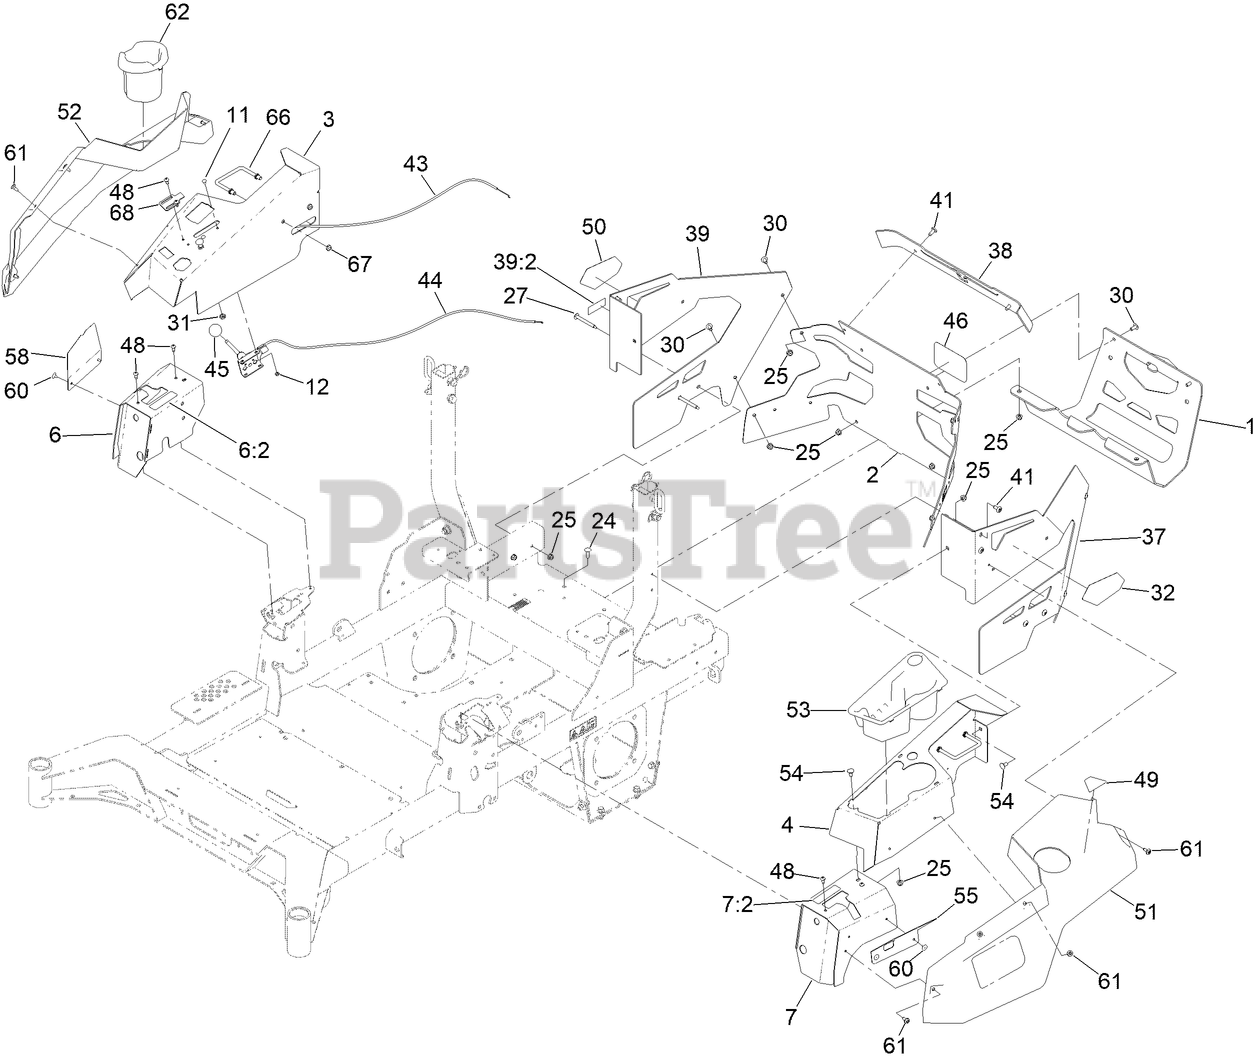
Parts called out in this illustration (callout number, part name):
1	GUARD-MUFFLER [BLACK]
2	REAR GUARD ASM
3	CONSOLE-RH
4	CONSOLE-LH
6	RH COVER ASM
6:2	DECAL-CONTROL, MOTION
7	LH COVER ASM
7:2	DECAL-CONTROL, MOTION
11	BOLT-CARR
12	NUT-LOCK, NI
24	SCREW-CARR
25	NUT-HF, NI
27	SCREW-TORX
30	SCREW-TORX
31	NUT-HJ
32	DECAL - 4000 SERIES, LH
37	GUARD-REAR, LH
38	GUARD-REAR, TOP
39	RH REAR GUARD ASM
39:2	DECAL-ARRESTOR, SPARK
43	CABLE-CONTROL, CHOKE
44	CABLE-CONTROL, THROTTLE
45	KNOB-BALL
48	SCREW-TPH THD FORM
49	DECAL-FILL, FUEL
50	DECAL-4000 SERIES, RH
51	SIDE POD, LH
52	SIDE POD, RH
53	CUP HOLDER
54	SCREW-CARR
55	PLATE-COVER, LH FRONT
58	PLATE-COVER, RH FRONT
60	RIVET-TRIFOLD
61	SCREW-SHOULDER
62	CUPHOLDER-RH
66	ROD-SUPPORT, POD
68	PLATE-THROTTLE STOP
